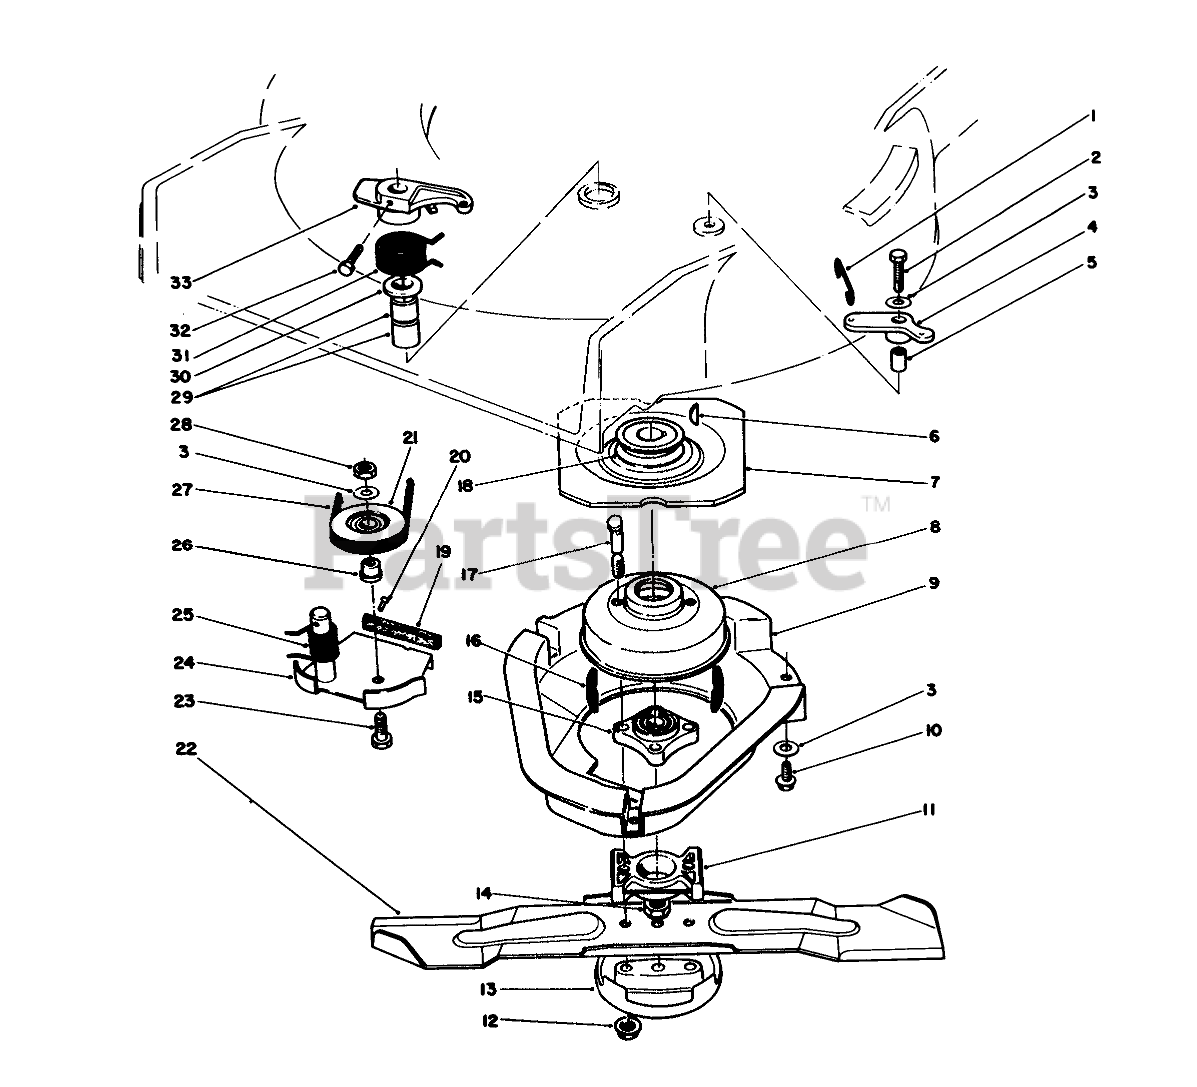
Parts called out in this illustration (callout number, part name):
1	LINK-CONTROL
2	SCREW-HH
3	WASHER-PLAIN
4	BELLCRANK
5	SLEEVE-BELLCRANK
6	KEY-WOODRUFF
7	Flywheel
8	Drum-Brake
9	SHIELD BBC
10	SCREW-HWHTF
11	Spacer-Blade
12	NUT-LOCK
13	Anti Scalp Cup
14	NUT-LOCK, NI
15	HUB ASM
16	DAMPENER-VIBRATION
17	BOLT-BLADE
18	PULLEY
19	Pad-Brake
20	.185 DIA X .375 RT +
21	PULLEY-IDLER
22	BLADE-21in
23	SCREW-HH
24	Brake Plate (Incl. Ref. #19 & 20)
25	SPRING-TORSION
26	HUB-PULLEY, IDLER
27	V-BELT
28	NUT-LOCK, NI
29	BEARING
30	WASHER
31	SPRING-TORSION
32	SCREW-HH
33	LEVER
